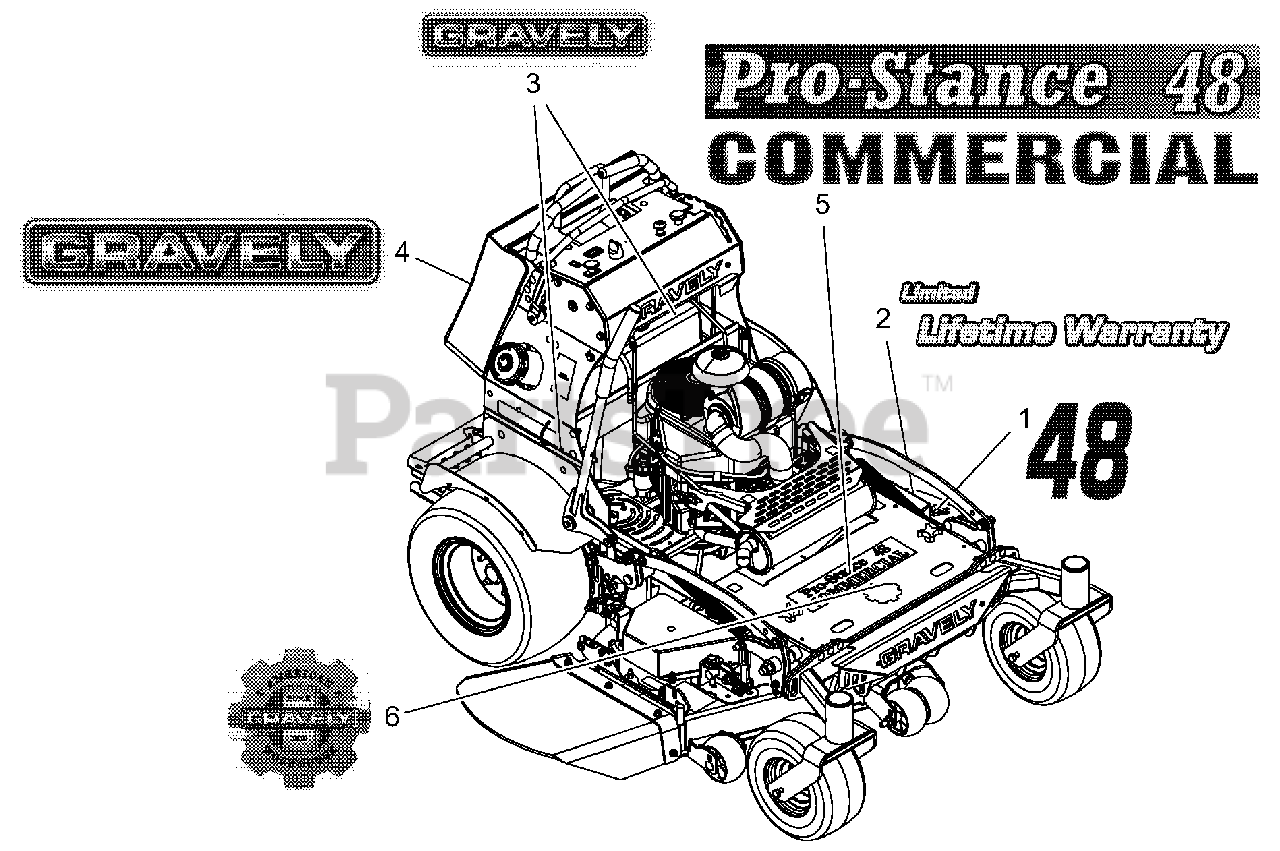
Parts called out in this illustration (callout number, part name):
1	DECAL, 48"
2	DECAL, LIMITED LIFETIME WARRANTY REV
3	DECAL, 9.5" GRAVELY LOGO
4	DECAL, FUEL TANK-GRAVELY
5	DECAL, PROSTANCE 48"
6	DECAL, GRAVELY HERITAGE-LARGE
